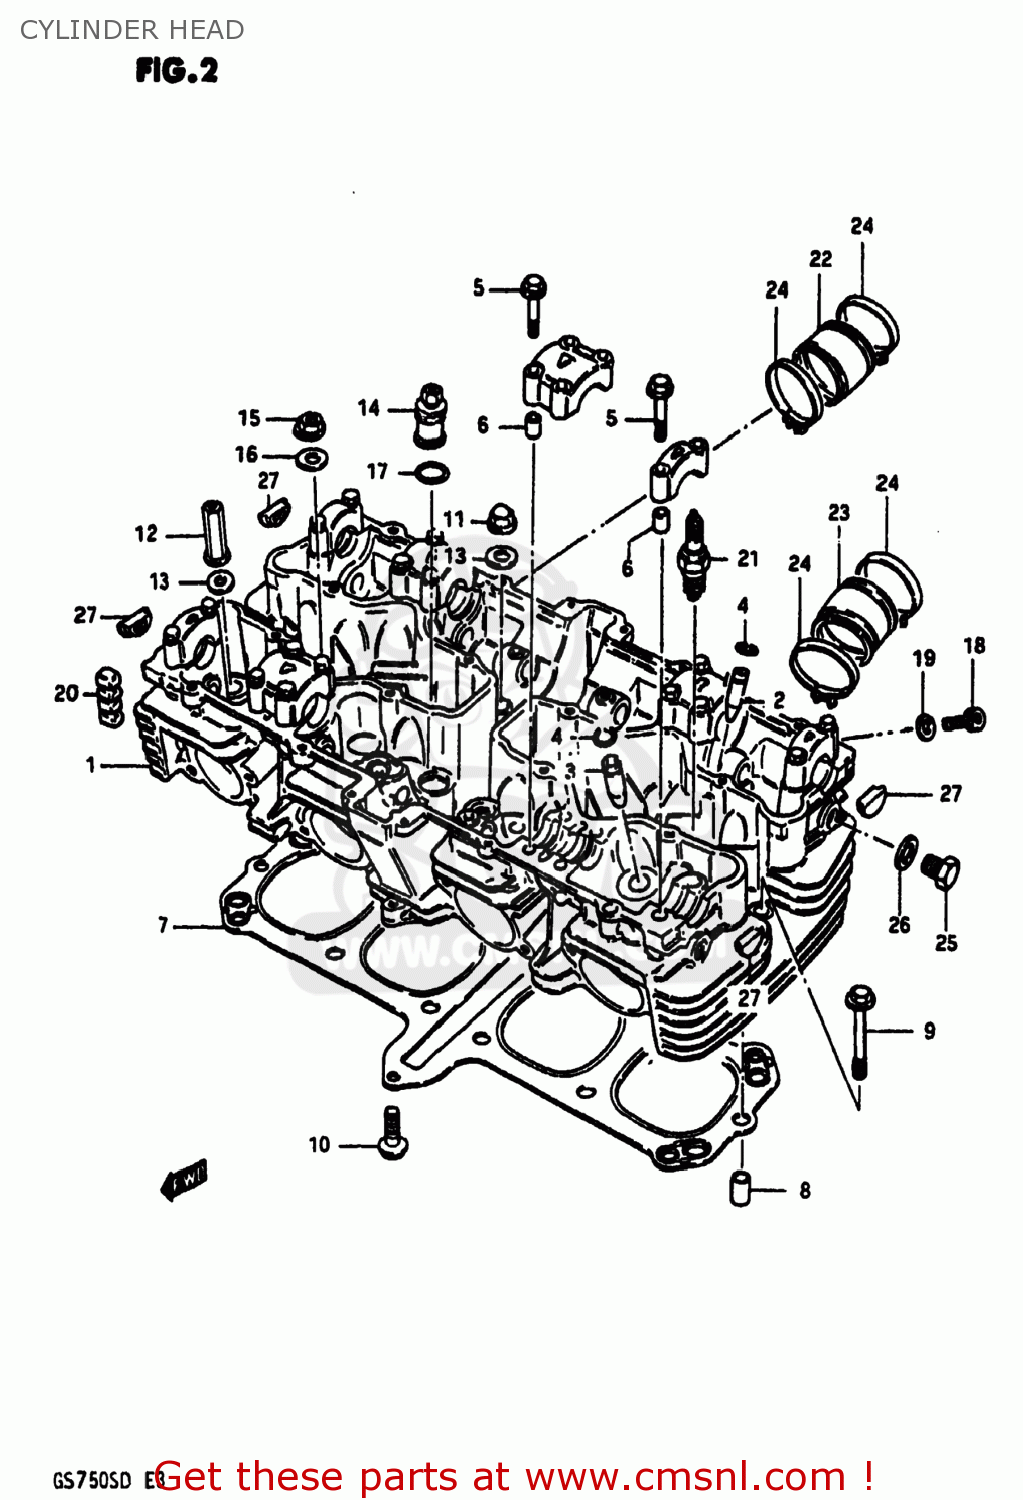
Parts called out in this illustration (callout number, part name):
1	HEAD ASSEMBLY,CYLINDER
2	GUIDE,INTAKE VALVE
3	GUIDE,INTAKE VALVE
4	RING,SNAP
5	BOLT(6X39)
6	PIN(6.2X8X11)
7	GASKET,CYLINDER HEAD (NAS)
8	PIN
9	BOLT 6X55
10	BOLT 6X30
11	NUT
12	NUT
13	GASKET(10.5X22X2) (NAS)
14	NUT,CYLINDER HEAD SEAL
15	NUT
16	WASHER(10.5X22X2.3)
17	O RING(D:2.4,ID:16.8)
18	BOLT
19	GASKET(5.3X9.3X1.2) (NAS)
20	PAD,CYLINDER
21	SPARK PLUG D8EA
22	PIPE,INTAKE,R
23	PIPE,INTAKE
24	CLAMP
25	PLUG (14X12)
26	GASKET(14X19.2X2) (NAS)
27	PLUG
